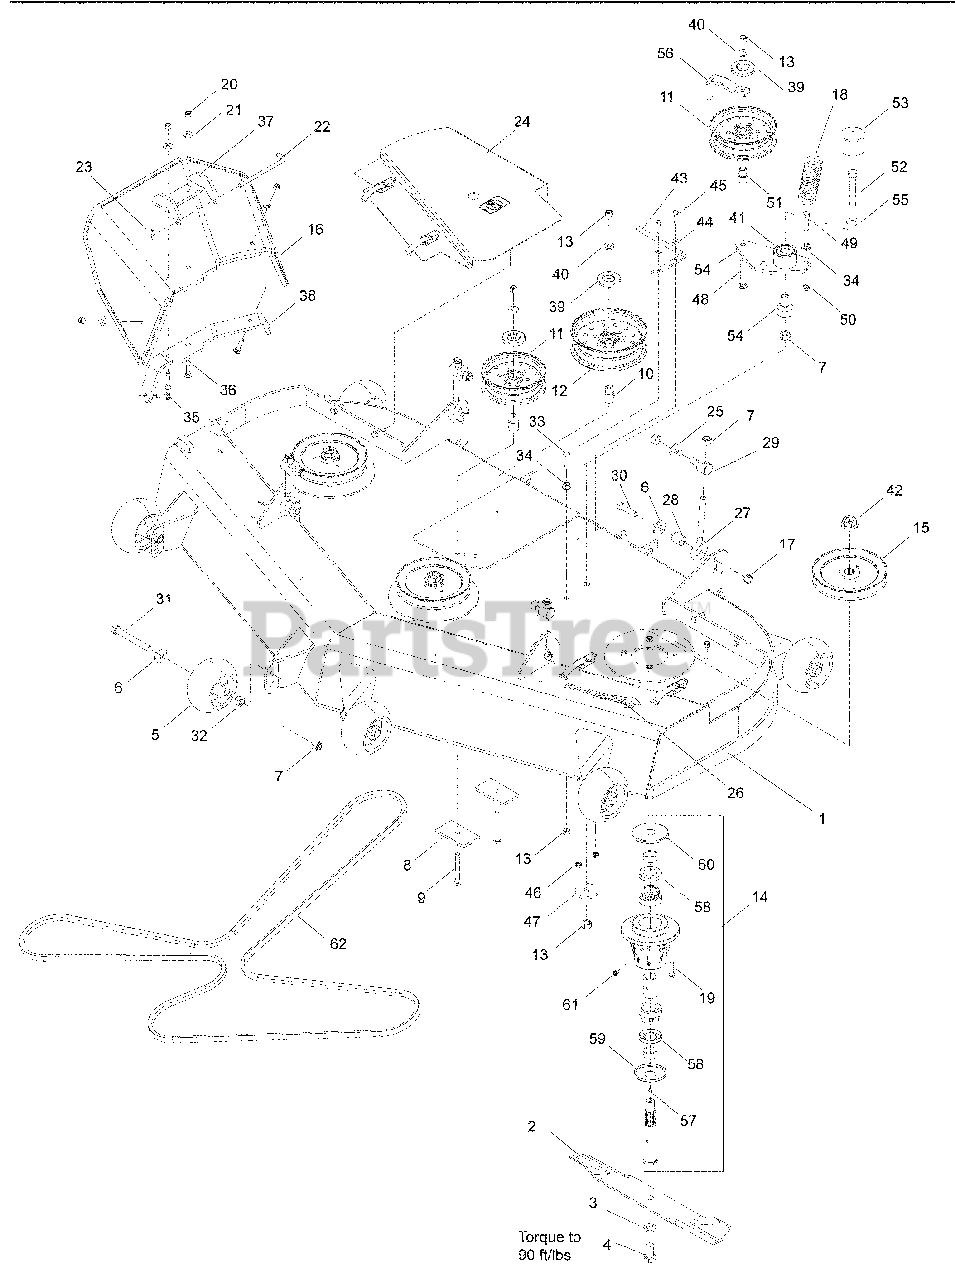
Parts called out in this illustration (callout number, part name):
1	DECK w/DECALS
2	BLADE, 21"
3	WASHER 5/8 SLW
4	HCS 5/8-18 x 1¼
5	WHEEL, GAUGE
6	WASHER ½ FLAT
7	NUT ½-13 NYLOC
8	PAD, PAINTED
9	HCS 3/8-16 x 3
10	BUSHING, IDLER
11	PULLEY, IDLER
12	PULLEY, IDLER (WIDE)
13	NUT 3/8-16 HEX NYLOC
14	HOUSING ASSM
16	CHUTE, DISCHARGE
17	NUT 7/16-14 HEX CTRLK GR A
19	HCS 5/16-18 x 1¼
20	NUT 5/16-18 HEX NYLOC
21	WASHER 5/16 STD FLT
22	PIN, CHUTE PIVOT
23	COTTER PIN 1/8 x ¾
24	BELT SHIELD ASSM RT
25	WASHER ½ STD FLT
26	DECAL, TUNNELRAM
30	HCS 7/16-14 x 1¾
31	HHB ½-13 x 4
32	NUT ½-13 HEX
33	HCS 3/8-16 x 1¼
34	NUT 3/8-16 HEX WHIZLK
35	RHSNB 5/16-18 x 1¼
36	RHSNB 5/16-18 x 1½
37	PIVOT BRACKET, CHUTE
38	REINFORCEMENT
39	SHIELD, DUST
40	WASHER 3/8 SPECIAL
41	ARM, IDLER w/ BEARINGS
42	NUT ¾-16 FLANGE
43	GUIDE, BELT
44	WASHER ½ STD FLT
45	HCS ¼-20 x 1
46	NUT ¼-20 HEX FLANGE
47	WASHER, SUPPORT
48	RHSNB 3/8-16 x 2¾
49	HCS 3/8-16 x 1½ GR 8
50	NUT 3/8-16 HEX JAM
51	BUSHING, IDLER
52	HCS ½-13 x 3¼
53	CAP, VINYL
54	BEARING, PIVOT
55	WASHER, ½ BELLEVILLE
56	GUIDE, BELT
58	SEAL, SHAFT
59	DUST CAP, BOTTOM
60	DUST CAP, TOP
61	POPPET, GREASE
62	BELT, DECK
